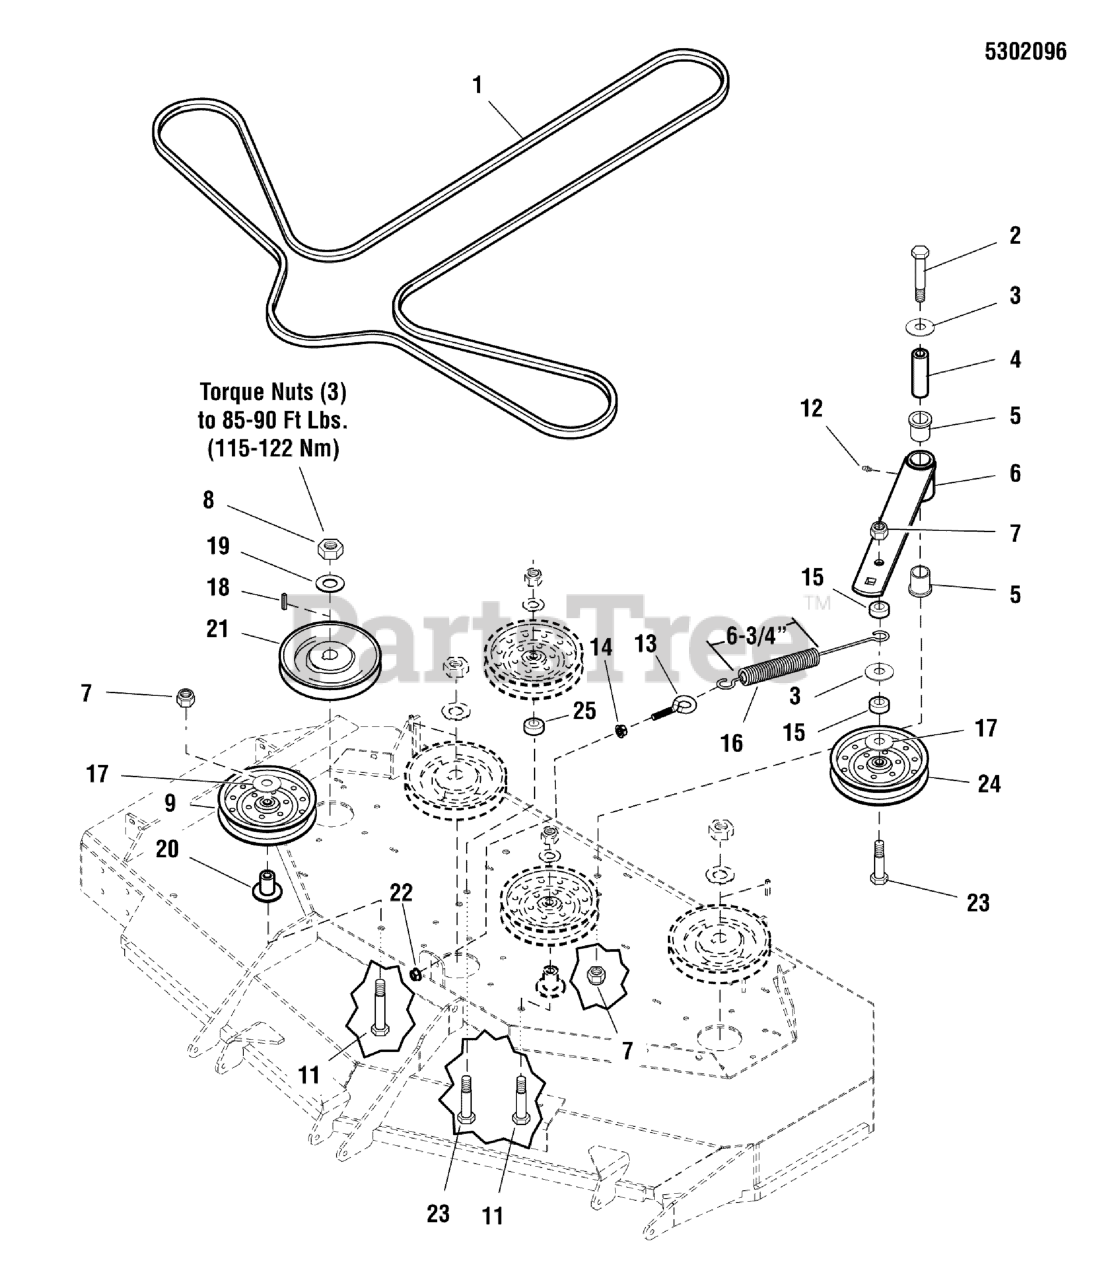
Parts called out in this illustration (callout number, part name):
1	BELT, 5V, 182.00"EL, LRG ARAMID, WRP, RC
2	BOLT, 1/2-13 X 4-1/2 GD5 YZ
3	WASHER, 1/2 USS
4	SPACER, .52 X 1.00 X 3.5
5	BUSHING, FLANGE
6	WELD, IDLER ARM - BLK
7	NUT, Hex Flange, Nylock, 1/2-13
8	NUT, 3/4-16 HEX
10	WASHER, 1/2 GD9 YZ
11	BOLT, 1/2-13 X 3" GD5 CZ
12	GREASE FITTING, 1/4-28 STRAIGHT
13	EYE BOLT, 3/8-16 X 6, 3.0 THREAD
14	NUT, 3/8-16 HEX JAM
15	SPACER, .52 X 1.00 X .44, CZ
16	SPRING-EXTENSION, SWIVEL END
17	SHIELD, PULLEY BEARING
18	KEY, 1/4 SQ X 1-1/4
19	WASHER, 3/4 BELLEVILLE
20	IDLER MOUNT
21	PULLEY, 6.93 EOD X 25MM, SPLIT
22	NUT, 3/8-16 HEX NYLOCK FLANGE
23	BOLT, 1/2-13 X 2-3/4 GD5 CZ
25	SPACER, .51 X 1.75 X .75
